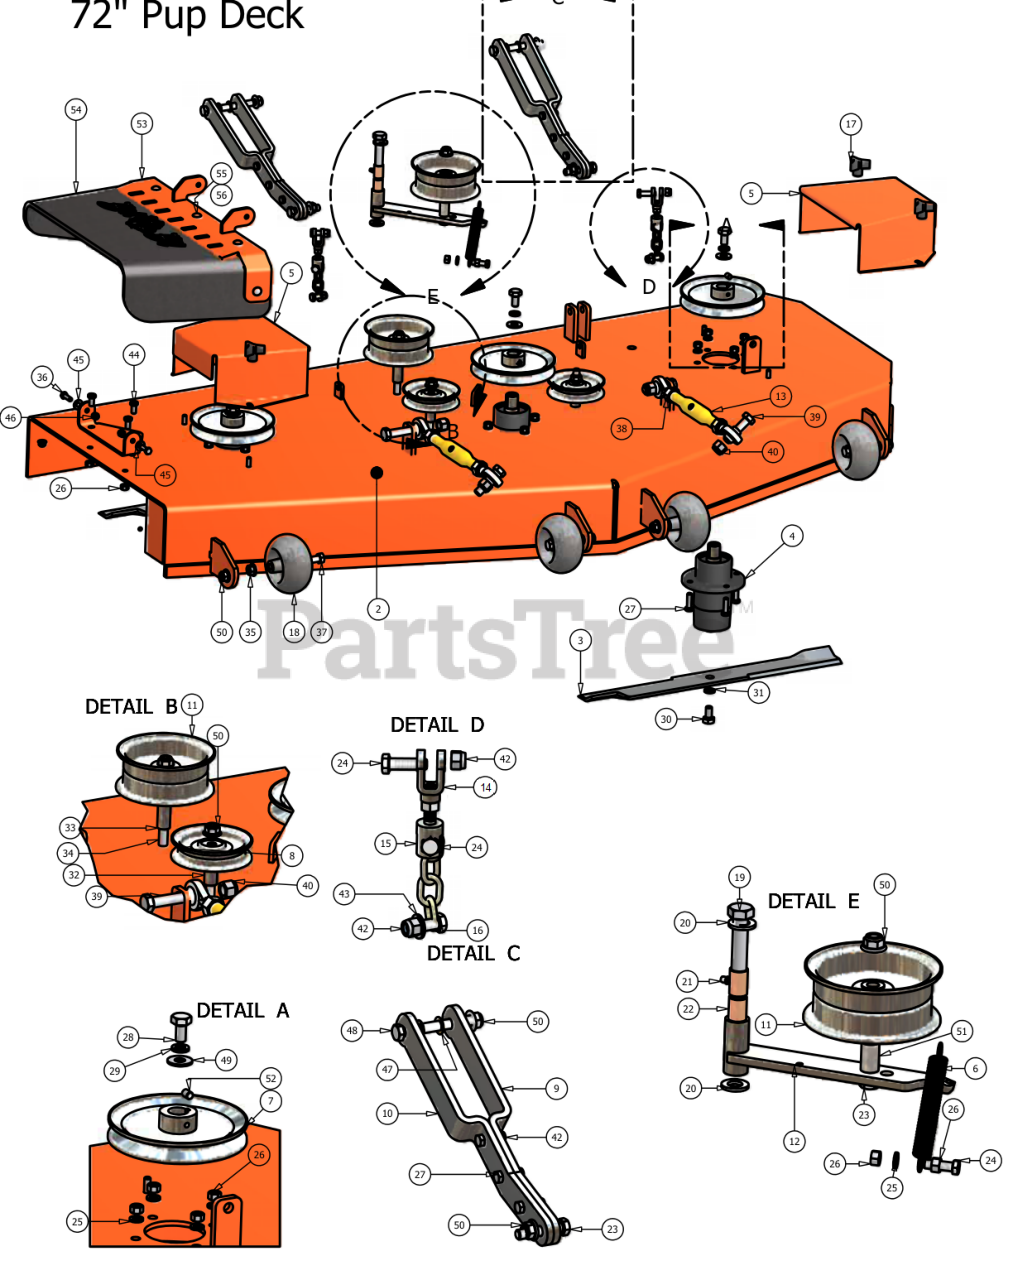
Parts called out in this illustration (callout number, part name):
1	72" Deck Belt-B189
3	72" Fusion Blade
5	Pulley Guard
6	Deck Idler Spring
7	7" Deck Pulley
8	4 3/4" Idler Pulley
9	Deck Support Arm (Right)
10	Deck Support Arm (Left)
11	5 3/4" Flat Idler Pulley
12	Deck Idler Arm
13	Turnbuckle
14	Female Yoke
17	5/16" Knob
18	Anti-Scalp Rollers
19	5/8" x 4" Hex Bolt
20	.635 ID Plastic Washer
21	Grease Fitting (Drive-In Type)
22	5/8" ID x 1 1/8" Brass Bushing
23	1/2" x 2 1/2" Hex Bolt
24	3/8" x 1 1/4" Hex Bolt
25	3/8" Lock Washer
26	3/8" Hex Nut
27	3/8" x 1 1/4" Hex Bolt
28	1/2" x 1 1/2" Fine Thread Bolt
29	1/2" Lock Washer
30	5/8" x 1.5" Fine Threaded Bolt
31	5/8" Lock Washer
32	1 1/2" Pulley Spacer
33	1 3/4" Pulley Spacer
34	1/2" x 3 1/2" Bolt
35	1/2" Flange Nut
36	5/16" x 1" Hex Bolt
37	1/2" x 4" Bolt (Grade 8)
38	3/4" Left Handed Nut
39	5/8" x 2 1/2" Hex Bolt
40	5/8" Nylock Nut
41	3/8" Fine Threaded Jam Nut
42	3/8" Nylock Nut
43	3/8" Flat Washer
44	3/8" x 3/4" Hex Bolt
45	.360 ID Plastic Washer
46	5/16" Nylock Nut
47	1/2" Brass Washer
48	1/2" x 4 1/2" Bolt
49	1/2" Cupped Washer
50	1/2" Flange Lock Nut
51	1 1/4" Pulley Spacer
52	3/8" Set Screw
53	2007 Hanger Plate
54	Rubber Side Discharge
55	5/16" x 1 1/2" Carriage Bolt
56	5/16" Nylock Flange Nut
57	2007 Lower Hanger Plate
